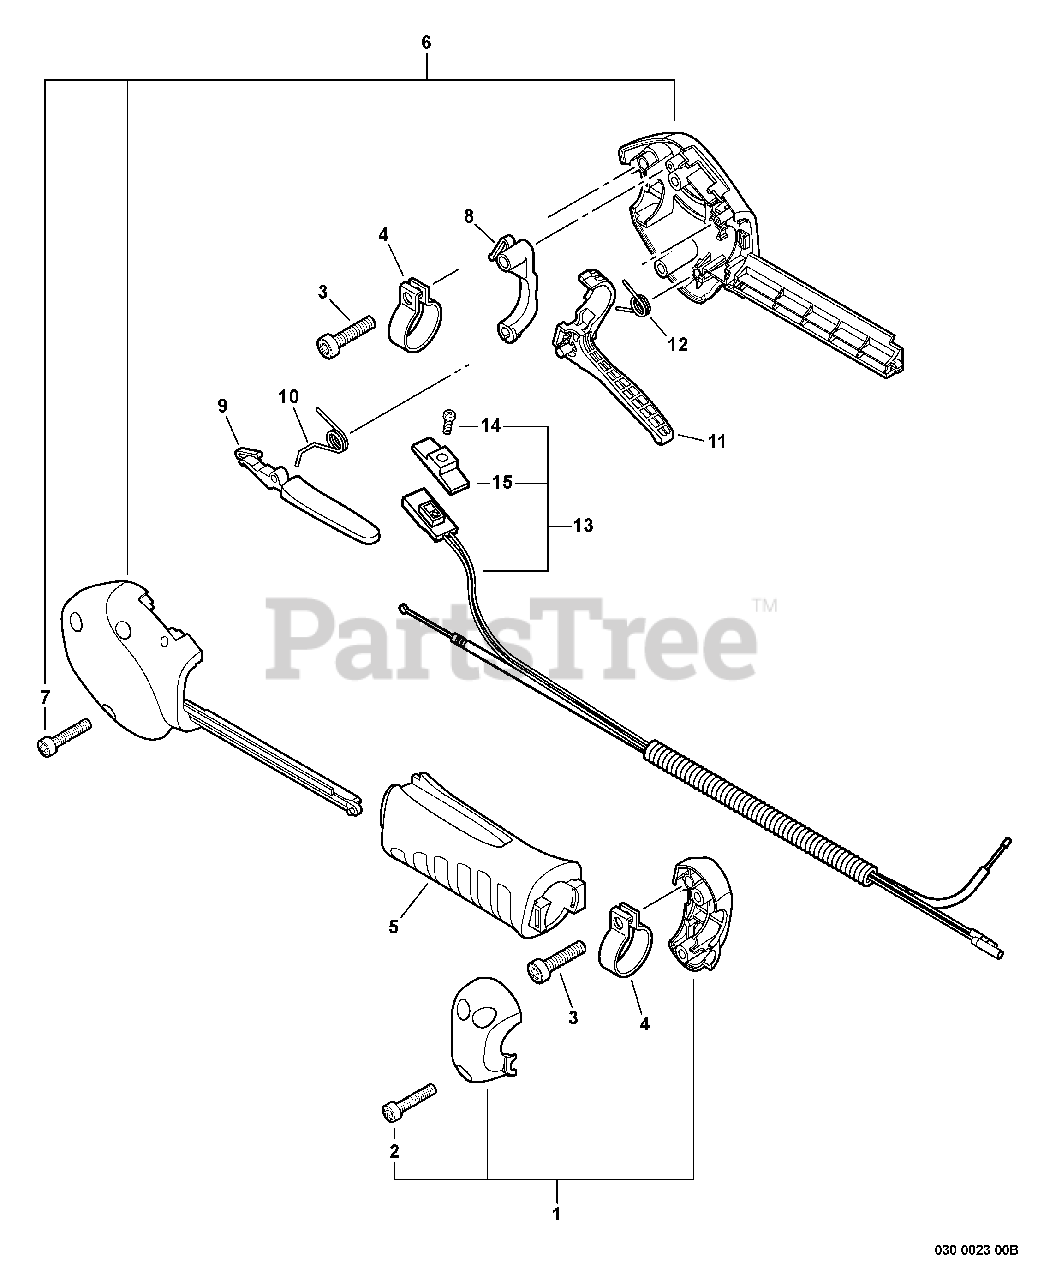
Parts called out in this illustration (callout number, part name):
1	HANDLE BRACKET KIT
2	SCREW - 4X20 -- TAPPING
3	SCREW - 5X20
5	GRIP, HANDLE
6	CONTROL HANDLE KIT
7	SCREW - 4X20 -- TAPPING
8	LOCKOUT, THROTTLE
9	LEVER, TRIGGER LOCKOUT
10	SPRING, LOCKOUT LEVER
11	TRIGGER, THROTTLE
12	SPRING, TRIGGER
13	CONTROL CABLE ASSY
14	SCREW - 3X10
15	KNOB, SWITCH - ORANGE
